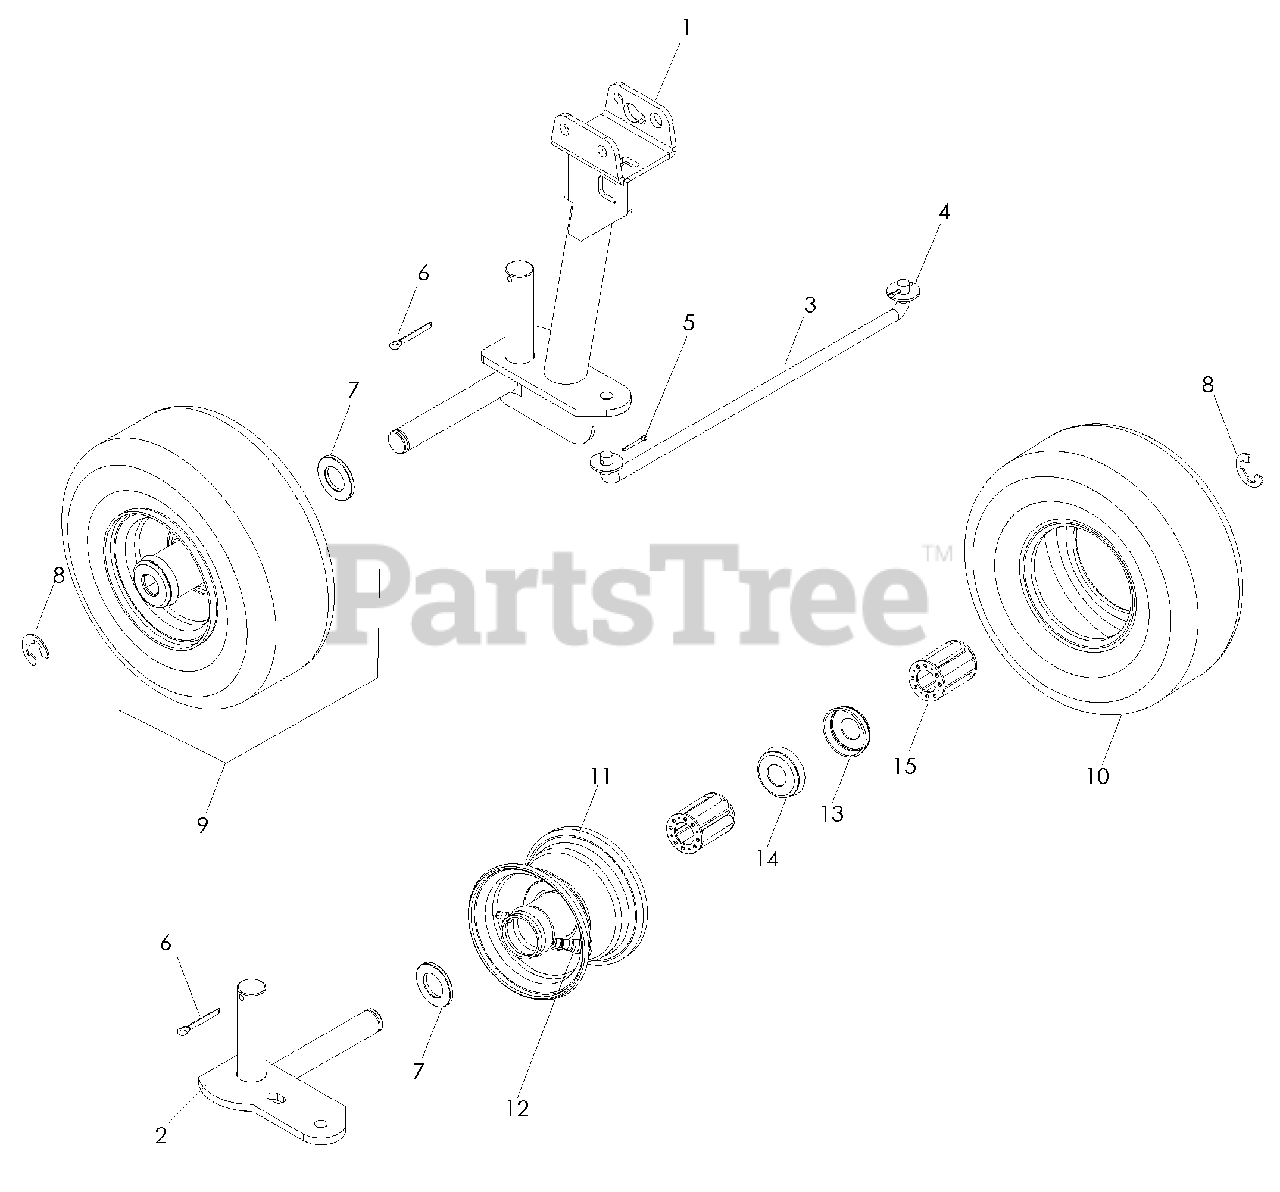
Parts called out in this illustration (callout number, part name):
1	ARM WELD, RH
2	ARM WELDMENT LH
3	STEERING ROD
4	WASHER 3/8 STD FLT
5	COTTER PIN 3/32 x 3/4
6	COTTER PIN 5/32 x 1 1/4
7	WASHER 3/4 FLAT SAE
8	E-RING 3/4
9	WHEEL ASSEMBLY
11	RIM ASSEMBLY
12	AIR VALV E
13	END CAP
14	END CAP, NOTCHED
15	BEARING, ROLLER
